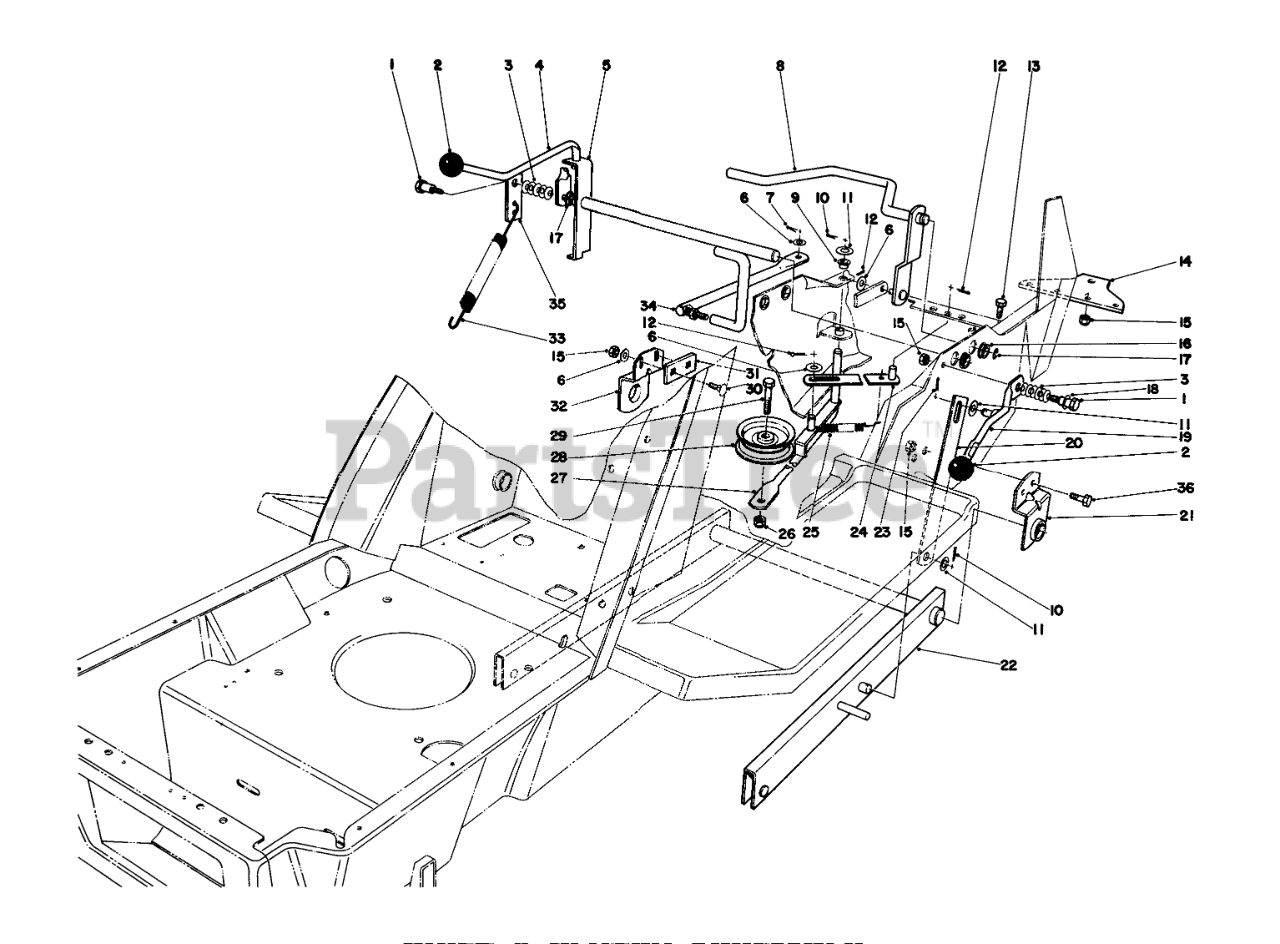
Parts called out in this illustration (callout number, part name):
1	BOLT-SHOULDER
3	WASHER-BELLEVILLE
4	SHIFT LEVER BO
5	Shim Lever
6	WASHER-PLAIN
7	PIN-COTTER
8	CLUTCH ACTUATOR WA B
9	BUSHING-NYLINER
10	PIN-COTTER
11	WASHER-FLAT
12	PIN-COTTER
13	SCREW-HHF
14	HITCH PLATE R
15	NUT-LOCK, CONE
16	Nyliner
17	E-RING
18	WASHER-FLAT
19	HOC HANDLE WA B
20	H.O.C. STRAP B
21	LH PIVOT BAR RET B
22	Bar-Pivot
23	PIN-COTTER
24	SPRING RET WA B
25	DECK TENSION SPRNG O
26	NUT-LOCK, CONE
27	IDLER ARM WA BO
28	IDLER PULLEY
29	SCREW-HH
30	BOLT-CARR
31	SPACER
32	RH PIVOT BAR RET B
33	TRACTION SPRING
34	SHIFT ARM BO
35	BRKT-COBALANCE SPRING
36	SCREW-HH
